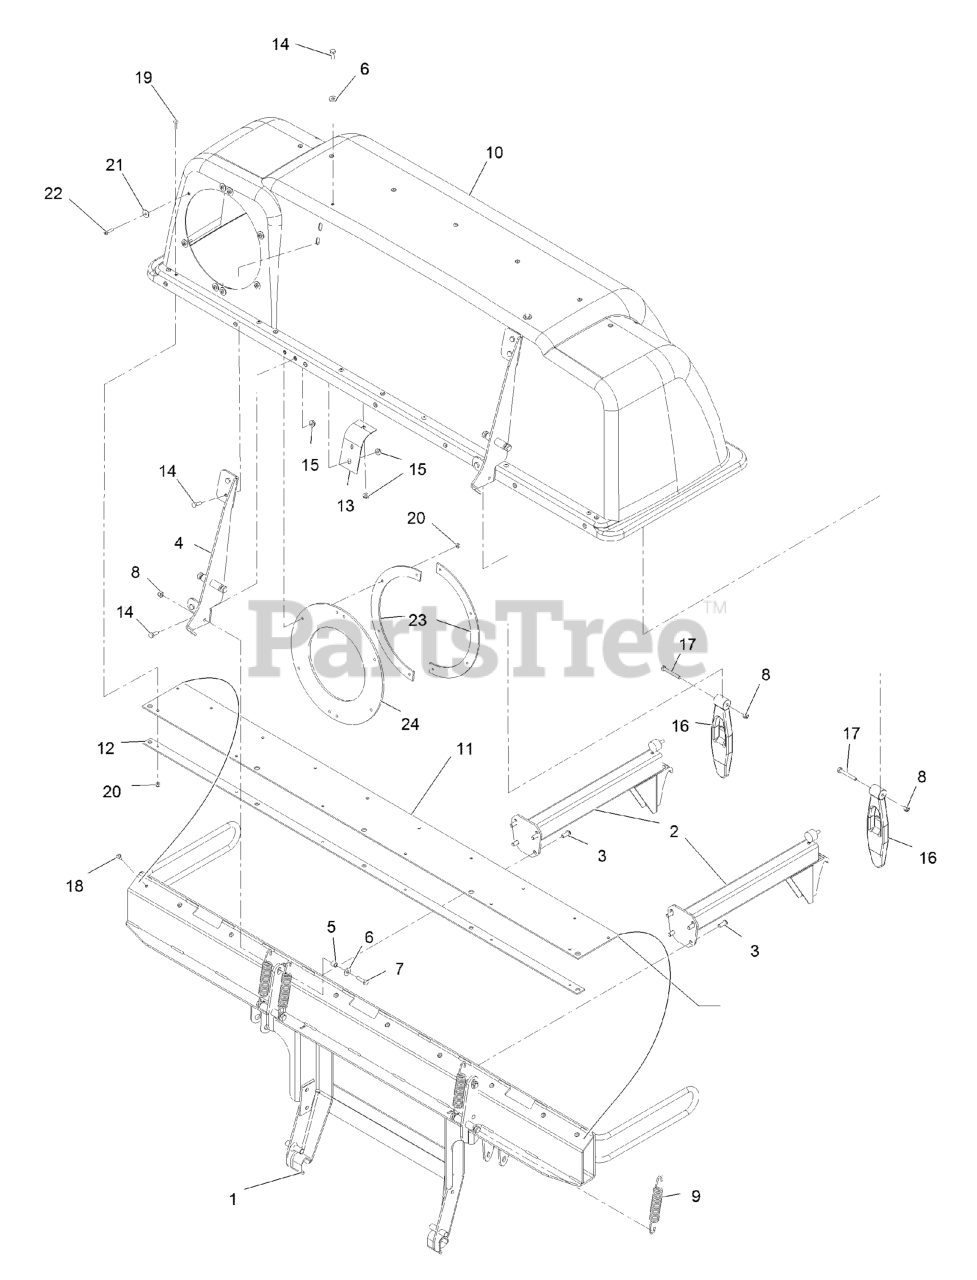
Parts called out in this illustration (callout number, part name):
1	FRAME-3-BAG
2	BAG SUPPORT ASM
3	SCREW-HSBH
6	WASHER-FLAT
7	SCREW-HH
8	NUT-LOCK, NI
9	SPRING-EXTENSION
10	ASM, HOOD
11	SEAL-HINGE
12	PLATE-BACKING
13	REINFORCEMENT-HOOD, BAGGE
14	SCREW-HH
17	SCREW-HH
18	RIVET-BLIND
19	SCREW-HEAD, TRUSS
20	NUT-LOCK, NI
21	WASHER-FLAT
22	SCREW-PPH
23	CLAMP-SEAL
24	SEAL-TUBE
